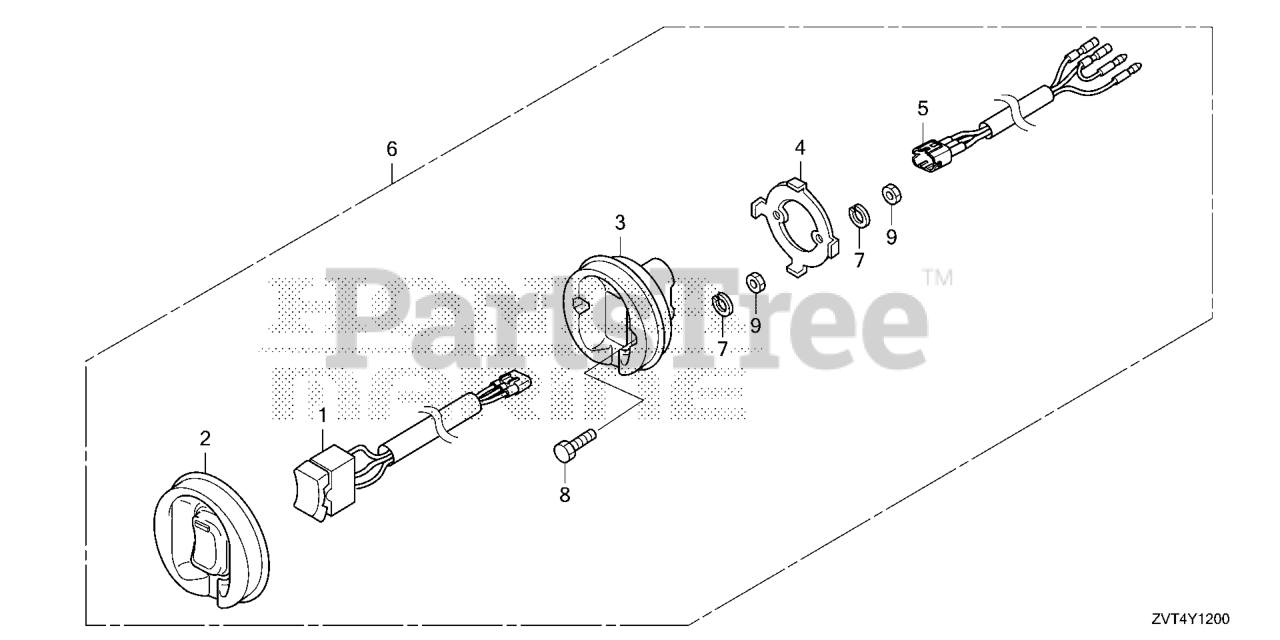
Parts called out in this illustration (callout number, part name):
1	SWITCH ASSY., TROLLING CONTROL (ENGINE NO.)
2	RUBBER, TROLLING CONTROL SWITCH PANEL (ENGINE NO.)
3	BODY, TROLLING CONTROL SWITCH PANEL (ENGINE NO.)
4	BRACKET, TROLLING CONTROL SWITCH PANEL (ENGINE NO.)
5	HARNESS, TROLLING CONTROL SWITCH PANEL (ENGINE NO.)
6	PANEL ASSY.
7	*90504-ZZ5-M00
8	BOLT, HEX. (4X20) (ENGINE NO.)
9	NUT, HEX. (4MM) (ENGINE NO.) (NOT AVAILABLE)
